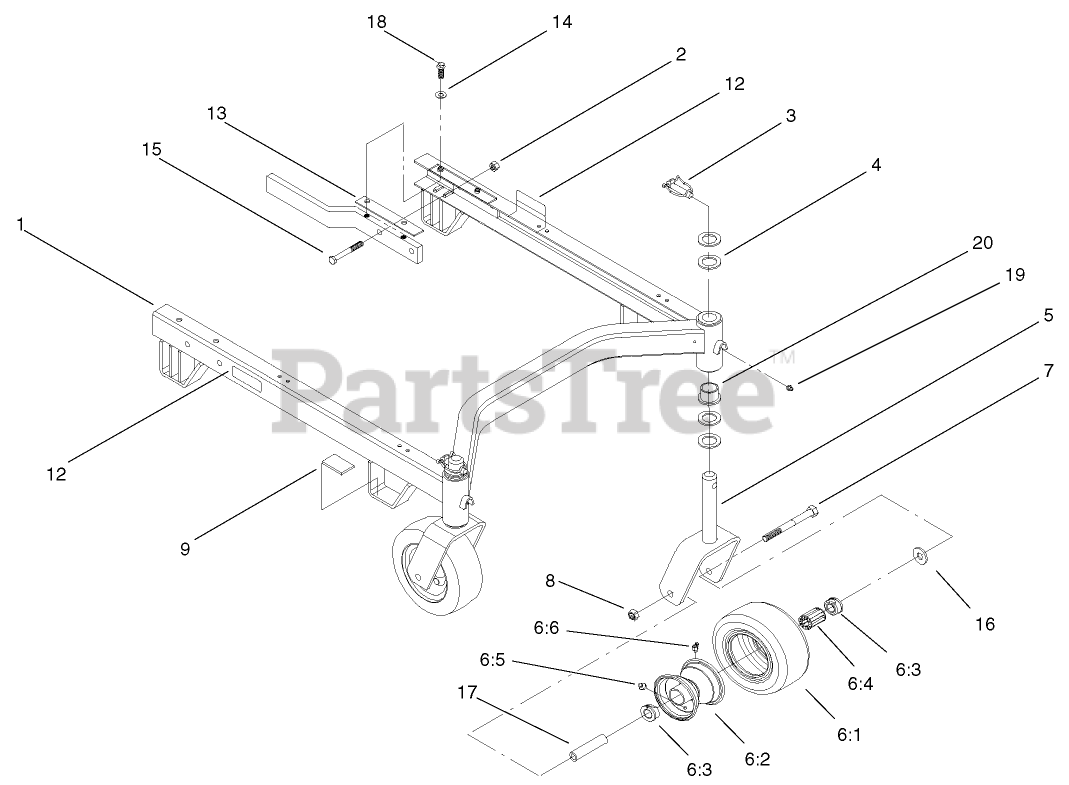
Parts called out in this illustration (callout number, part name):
1	SUSPENSION ASM, GM120
2	NUT-LOCK, CONE
3	PIN-LYNCH
4	WASHER-THRUST
5	FORK-CASTER, FRONT
6	CASTOR WHEEL ASM
6:1	TIRE-TUBELESS
6:2	RIM ASM
6:3	BEARING-OUTSIDE
6:4	BEARING-ROLLER
6:6	FITTING-LUBE, 45 DEG
7	SCREW-HH
8	NUT-HEX
9	CUSHION-RUBBER
12	DECAL-HOC
13	SHIM-CARRIER
14	WASHER-FLAT
15	SCREW-HH
16	WASHER-FLAT
17	SPANNER-TIRE
18	SCREW-HHF
19	FITTING-GREASE
20	BUSHING
